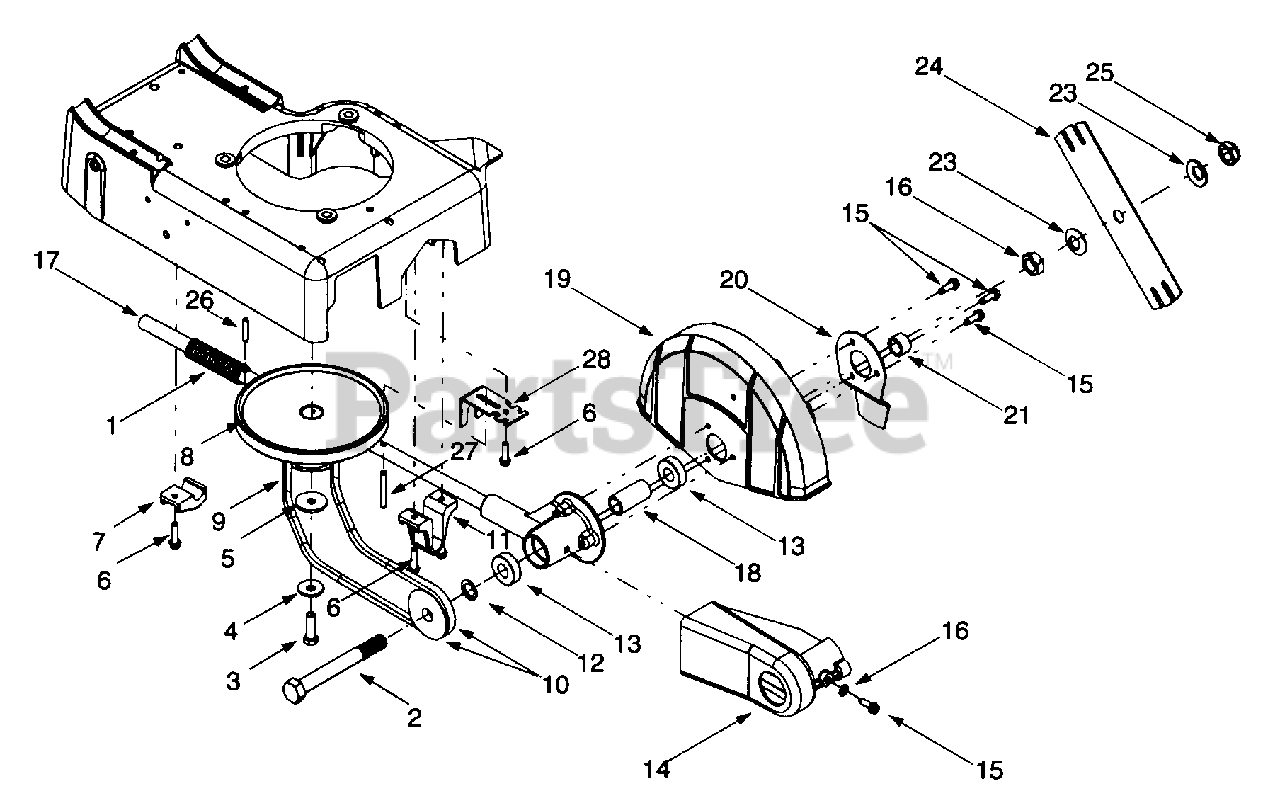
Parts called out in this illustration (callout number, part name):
1	Compression Spring
2	Hex Cap Screw, 5/8-18 x 5.25
3	Hex Cap Screw, 3/8-24 x 1.25
4	Bell Washer, .396 x 1.14 x.095
5	Flat Washer, .38 x 1.38 x .12
6	Hi-Lo Tap Screw, 1/4-15 x 1.0
7	Rear Rod Holder
8	Flywheel/Pulley Combination
9	V-Belt
10	Sheave, .6255 x .6295
11	Front Rod Holder
12	Flat Washer, .635 x .93 x .06
13	Ball Bearing, .62 x 1.38 x .44
14	Belt Guard
15	Self-Tapping Screw, 1/4-20 x .75
16	Flat Washer, .281 x .50 x .063
17	Spindle Bearing Housing w/ Insert
18	Spacer, .628 x .875 x 1.818
19	Blade Guard
23	Bell Washer, .64 x 1.25 x .18
25	Nylon Lock Jam Nut, 5/8-18
26	Spirol Pin, .25 x 1.25
27	Spirol Pin, .25 x 2.0
28	Stabilizer Bracket
